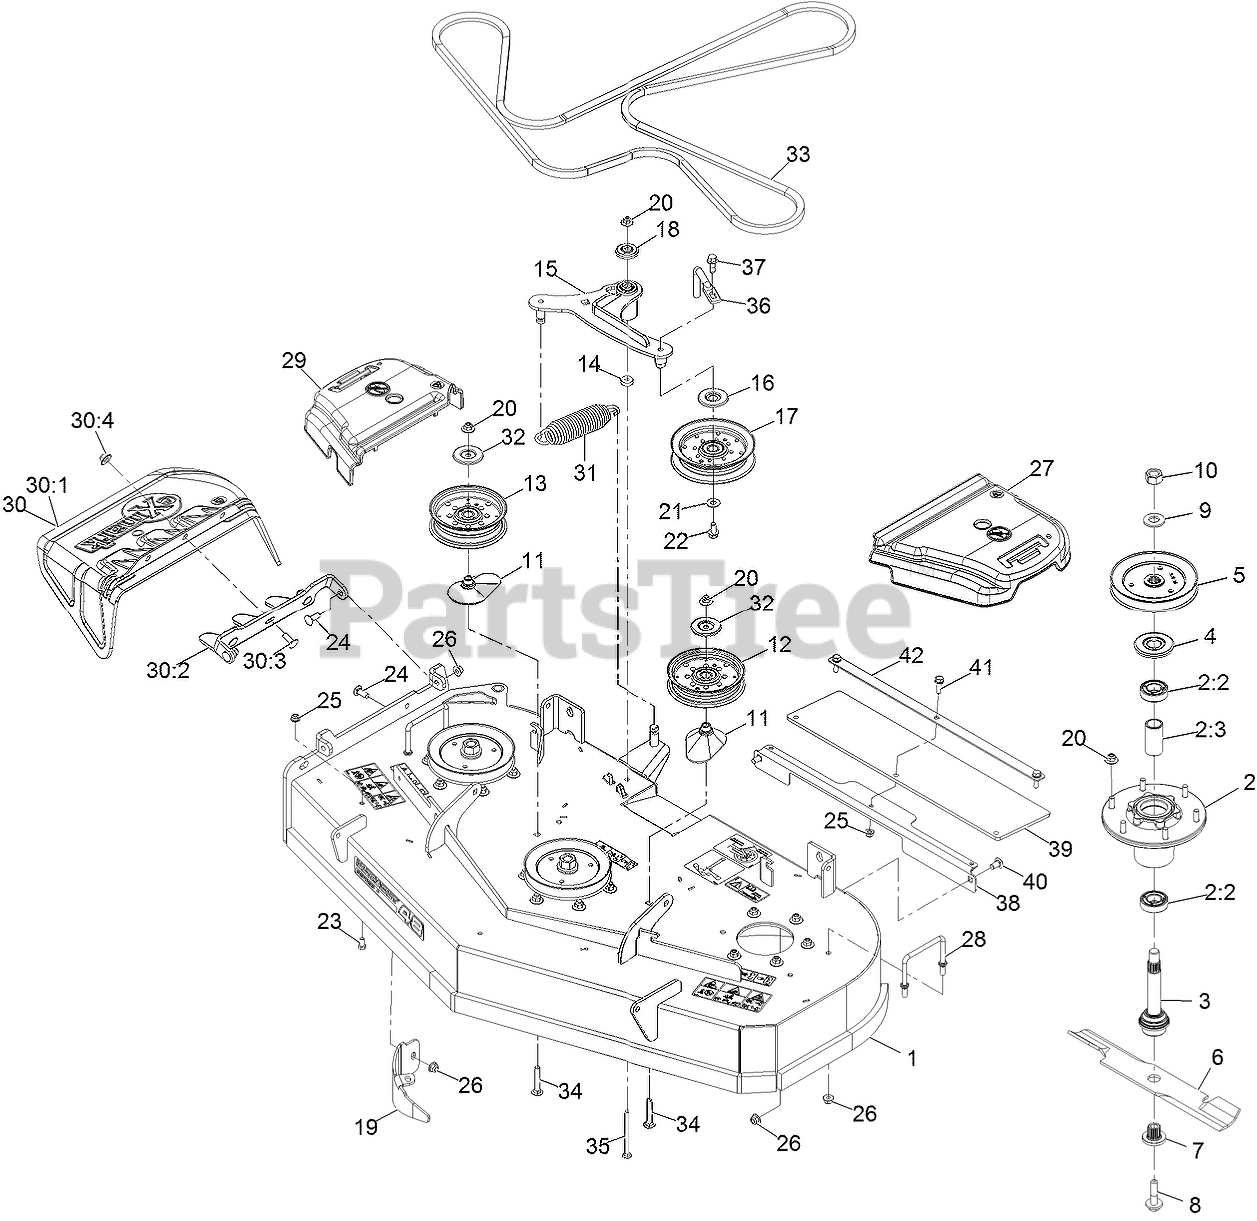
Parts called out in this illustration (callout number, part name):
1	ASM, Deck W/ Decals, 48"
2	ASM-CUTTER HSG WITH BEARINGS
2:2	BEARING-BALL
2:3	SPACER-BEARING
3	ASM-SPINDLE AND SEAL
4	GUARD,BEARING TOP .989
5	SHEAVE,BLADE DRIVE 5.90
7	BUSHING,SPLINED
8	SCREW,SEMS 1/2-20 X 2.19
10	NUT-HEX
11	SPACER-PULLEY
12	PULLEY-IDLER, FLAT
13	IDLER-PULLEY, FLAT 5.00X1
15	ASM, Deck Idler
16	SHIELD-GUARD, DUST
17	IDLER-PULLEY, FLAT
18	GUARD-TOP
19	BAFFLE-DOGLEG,LZS LZX VT4
20	Nut-Nyloc 3/8-16 Flg
21	WASHER-FLAT
22	SCREW-HHF
23	SCREW-HH
24	SCREW-CARR
25	NUT-HF, NI
26	NUT-HF, NI
27	COVER-BELT, LH
28	WIREFORM-COVER
29	COVER-BELT, RH
30	ASM,DISCHARGE CHUTE
30:1	CHUTE,DISCHARGE
30:2	BRACKET,DISCHARGE CHUTE
30:3	SCREW-CARR
30:4	Nut-Nyloc 3/8-16 Flg
31	SPRING-EXTENSION
32	SHIELD-DUST
33	BELT, 5V
34	Bolt-Carriage 3/8-16 X 2 1/4
35	SCREW-CARR
36	Guide, Belt
37	SCREW-HFH
38	Brkt, Heat Deflector
39	Shield, Heat
40	SCREW-CARR
41	SCREW-HHF
42	Brkt-Heat Deflector, Top
